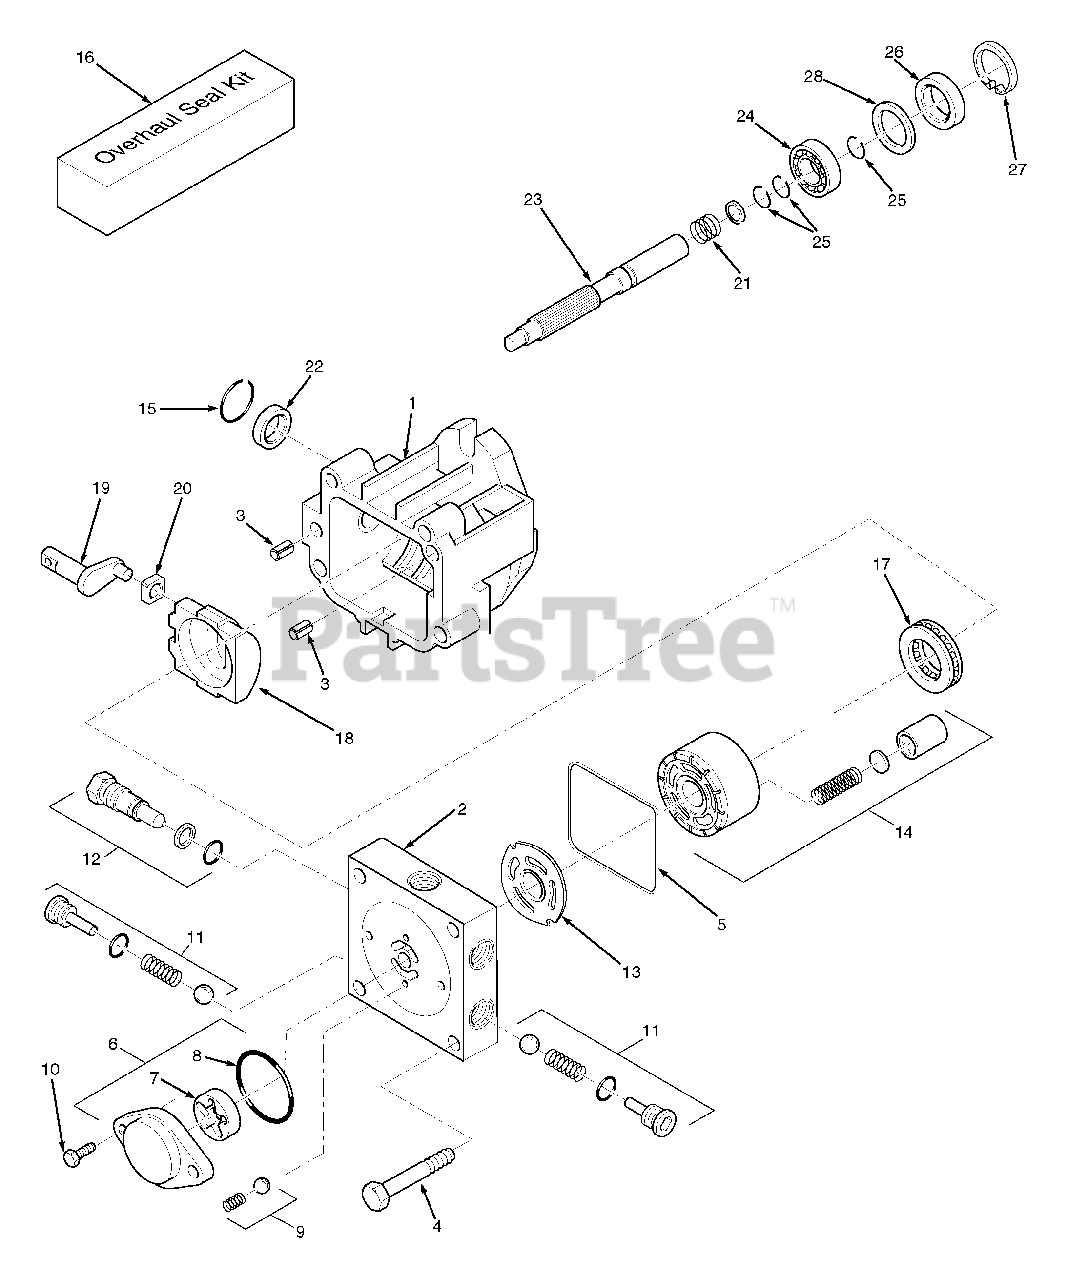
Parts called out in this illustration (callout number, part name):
1	Housing Kit
2	End Cap
3	Straight Headless Pin
4	Socket Head Screw
5	End Cap Gasket
6	Charge Pump Kit
7	Gerotor Assembly
9	Charge Relief Valve Kit
10	Socket Head Screw
11	Check Valve Kit
12	Bypass Valve Kit
13	Valve Plate
14	Cylinder Block Kit
15	Trunion Seal Retaining Ring
16	Overhaul Kit
17	Roller Thrust Bearing
18	Swash Plate
19	Trunnion Arm
20	Guide Slot
21	Block Spring
22	Lip Seal
23	Pump Shaft
24	Ball Bearing
25	Retaining Ring
26	Lip Seal
27	Retaining Ring
